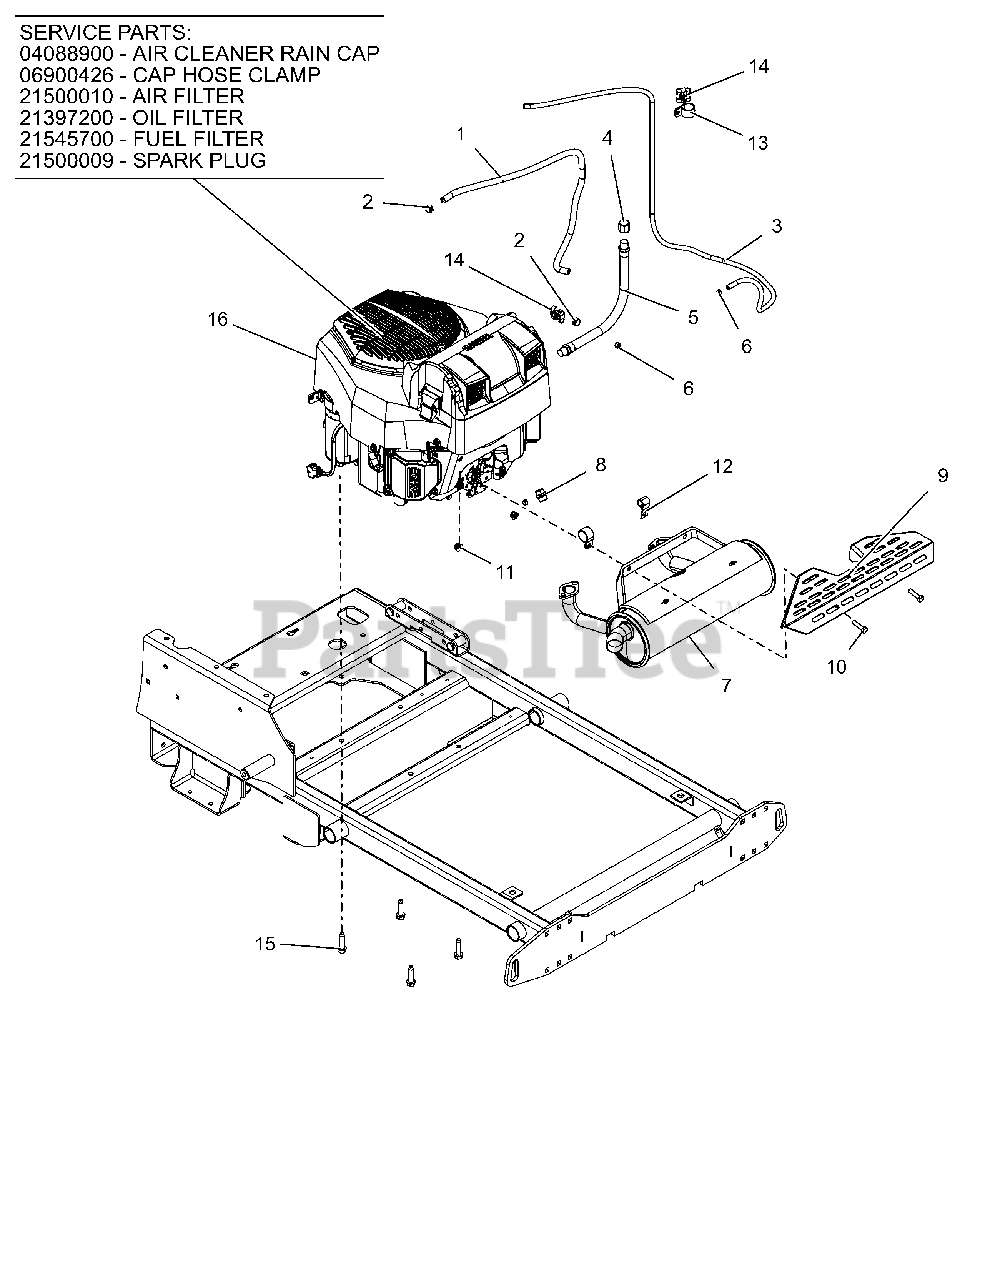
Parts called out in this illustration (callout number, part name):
1	HOSE, .25 LOW-PERM BULK GAS
2	CLAMP, FUEL LINE
3	HOSE, .188 LOW-PERM BULK GAS
4	PIPE CAP 3/8 NPT FEMALE
5	HOSE,HYD .38-14-0K M6N0-M6N0
6	CLAMP-HOSE, SPRING .188
7	MUFFLER, KOHLER EFI PRO-STANCE
8	PLUG, EXHAUST
9	GUARD, MUFFLER
10	@BLT-HEX .31-18X1.25 GR5 YWZC
11	@NUT-LK-NYL-FLG .31-18 YWZC
13	CLAMP, COUSHIONED STEEL REV
14	CLIP, T, .38-.50
15	@SCR-TAP .38-16X1.50 HWH TR YZ
16	ENGINE, KOHLER ZT730
16	CAP, KAW 11065-7025
16	CLAMP, HOSE #36 SS 1.813-2.75
16	AIR CLEANER, KOHLER CONFIDANT
16	FILTER, OIL - KOH CV20
16	FILTER-FUEL KOHLER COURAGE PRO
16	PLUG, SPARK KOHLER
